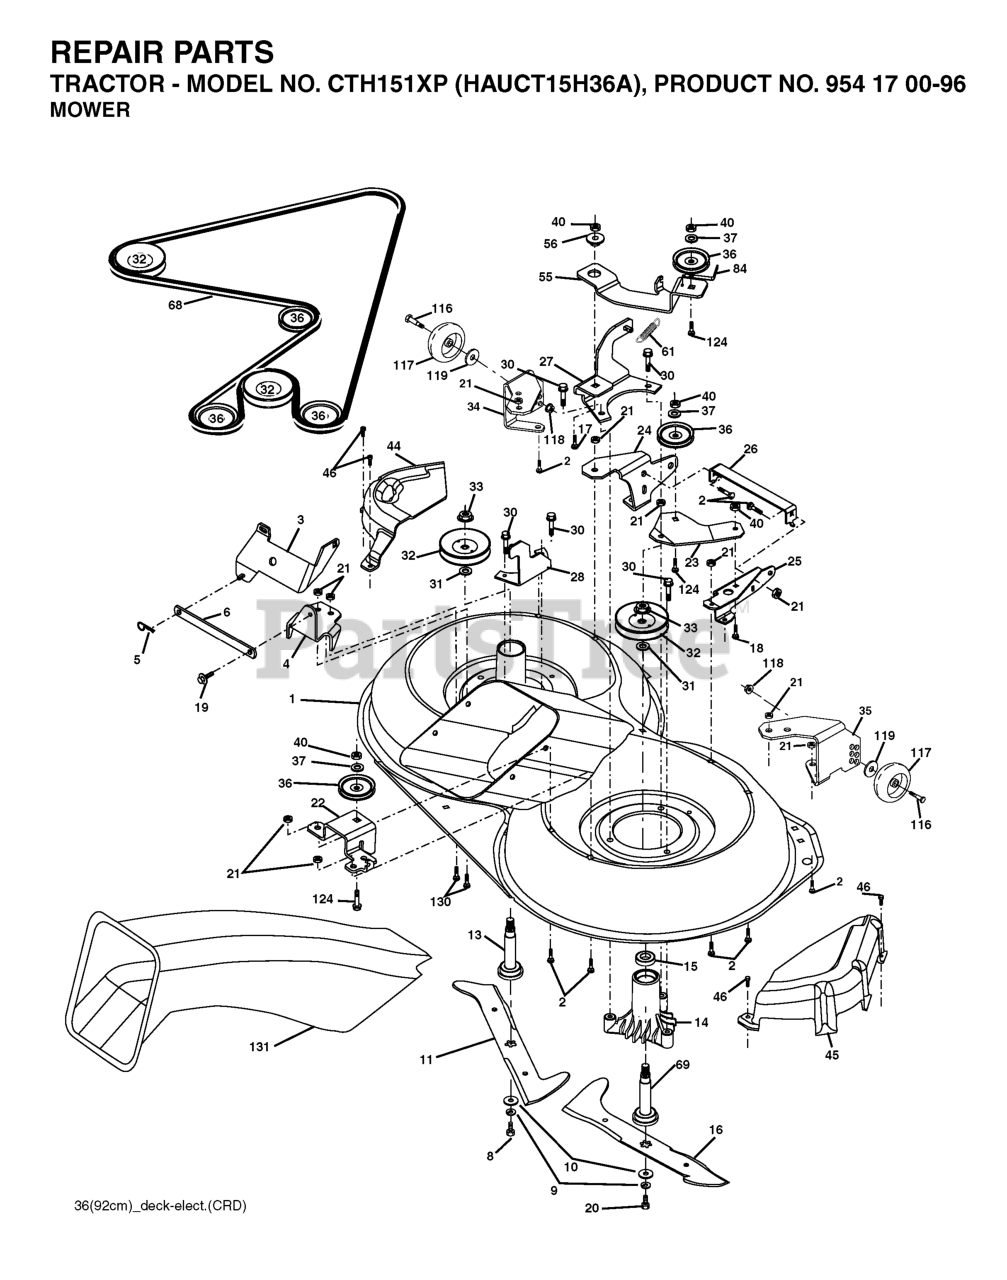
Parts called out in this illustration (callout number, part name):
1	MOWER HOUSING, DECK
2	RP BOLT 5/16-18 X3/4 ZN/YEL GR
5	RETAINER-SPRNG RB
6	BAR.SWAY.92.CRD
8	BOLT.3/8-24X1.25 GR8
9	LOCKWASHER
10	WASHER.BLADE
11	BLADE-LH 5PT STAR(CTH130)
13	SHAFT ASM VENT
14	HOUSING.MANDREL.VENTED (MACHD)
16	BLADE RH 6PT STAR(CTH130)
17	BOLT.3/8-14X1.25
19	BOLT SHD 5/16-18
20	BOLT.3/8-24X1.25GR8. LHTHRD
21	LOCKNUT
26	BRACE.SUPT.SUSP.FRT.CRD
30	SCREW, WASHER HEAD
31	WASHER
32	PULLEY, MANDREL
33	NUT, FLG TOPLOCK 9/16"
36	PULLEY.IDLER.4.25
37	WASHER
45	COVER.MANDREL.RH.CRD
46	SCREW.1/4-20X5/8
56	SPACER.RETAINER.MOWER
61	SPRING.TENSION.BELT
68	HEX-BELT
69	SHAFT.ASM.W/LWR.BRG.RH.THREAD
84	KEEPER, BELT IDLER
116	SHOULDER BOLT
117	WHEEL GAGE DONUT
118	LOCKNUT
119	WASHER.5/16.FLAT.STE.STD.
124	BOLT.3/8-16X1.50
130	BOLT.CARR.SQNK.5/16-18UNC.X3/4
131	CHUTE BAGGER
